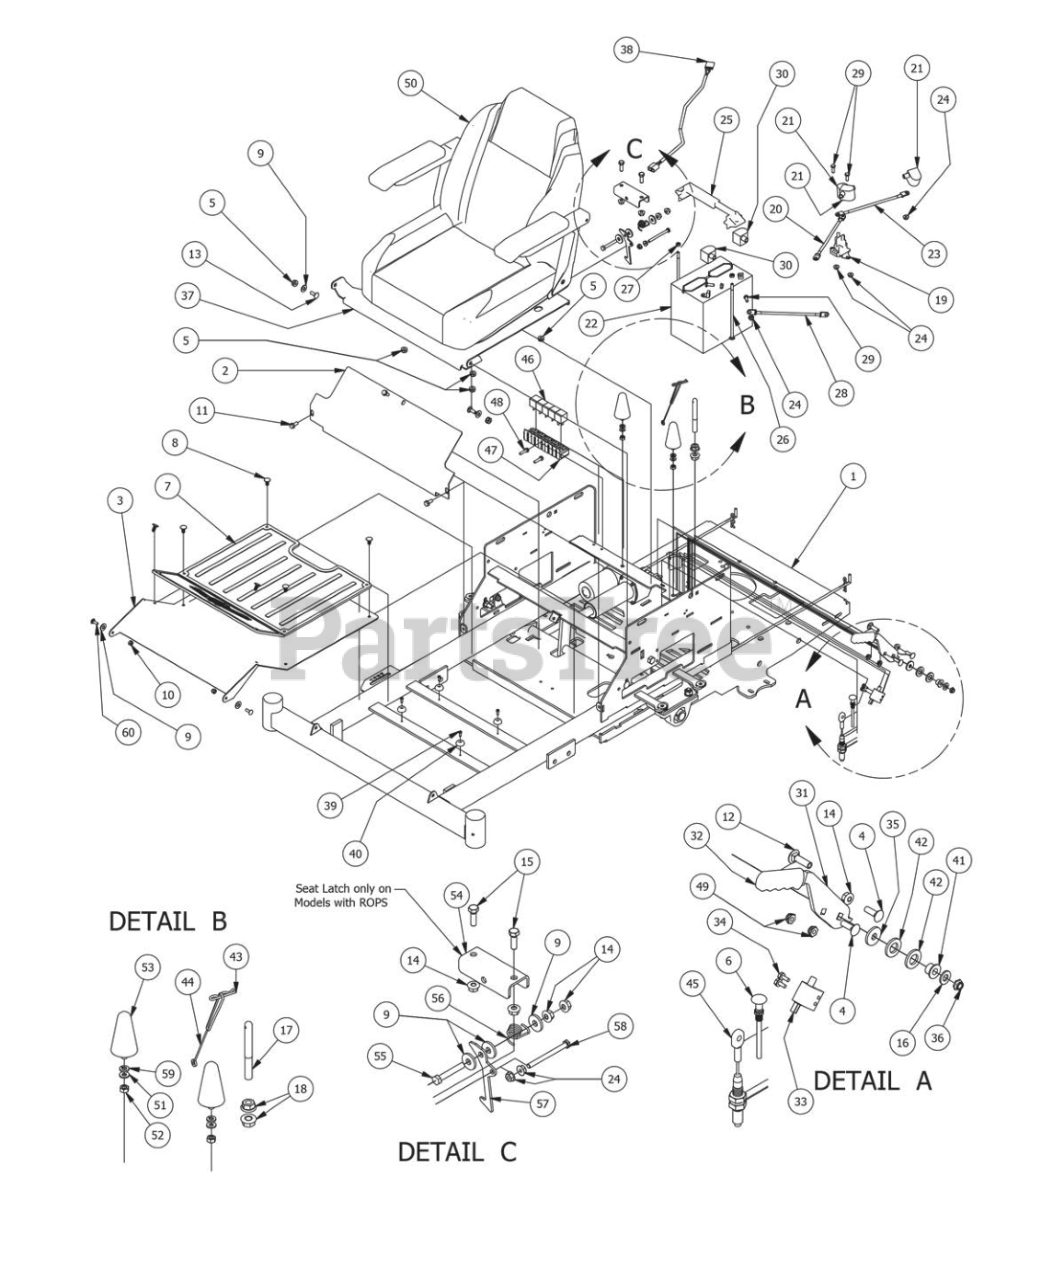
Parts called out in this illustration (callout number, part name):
1	ZT/CZT Frame 2013 Models
2	2013 ZT/CZT Cooler Cover
3	ZT/CZT FLOOR PANEL
4	5/16" x 1" Carriage Bolt
5	5/16-18 Nylon Flange Nut
7	Zt Floorboard Mat
8	Ratchet Fastener
9	.360 ID Plastic Washer
10	1/4" Nylock Nut
11	5/16 x 3/4 washer head type F screw
12	3/8" x 1 1/4" Carriage Bolt
13	5/16" x 7/8" Carriage Bolt
14	5/16" Flange Nut
15	5/16" x 1" Bolt
16	3/8" Flat Washer
17	Seat Braket Pin
18	1/2" Flange Nut
20	24 in red battery cable
23	12 in red battery cable
24	1/4-20 Hex Flange Nuts Zinc w/Serrations
25	Battery Hold Down
26	1/4-20 X 8 Carriage Bolt
27	1/4-20 Hex Nut
28	Starter to chassis cable
29	1/4-20 x 3/4 GR 5 Hex Bolts Zinc
30	Black Boot For ground cable
31	Brake Handle Cam Over
32	Rubber Brake Grip-cZT/ZT 2013
33	Safety Switch
34	12-24x 1/2 HWH Bolt
35	.390 ID Plastic Washer
36	3/8 Nylock Jam Nut 1/2 Nut
37	2013 ZT Seat Plate
38	Seat Switch Adapter
39	#10 x 1/2" Self Taping Screw
40	Button Bumper
41	Bronze Bushing SF-1220-8
42	.635 ID Plastic Washer
43	Seat latch pin
44	seat pin lanyard
45	Brake Cable
46	Relay Terminal
47	Harness-ZT Only 2008 and up
48	1/4 x 1 Hex Head tek screw
49	5/16-18 Nylock Jam Nut 1/2 Nut
50	2013 ZT Seat
51	1/4" Flat Washer
53	Rubber Cone-1621-153
54	ZT/CZT Seat Latch Bracket
55	5/16-18 X 2 Hex C/S (GR.5) ZC
56	Torsion Spring for Seat latch
57	Seat Latch Lever
58	1/4 x 3 Hex Bolt - Grade 8 - ACS
59	5/16" Lock Washer
60	1/4" x 3/4" Carriage Bolt
